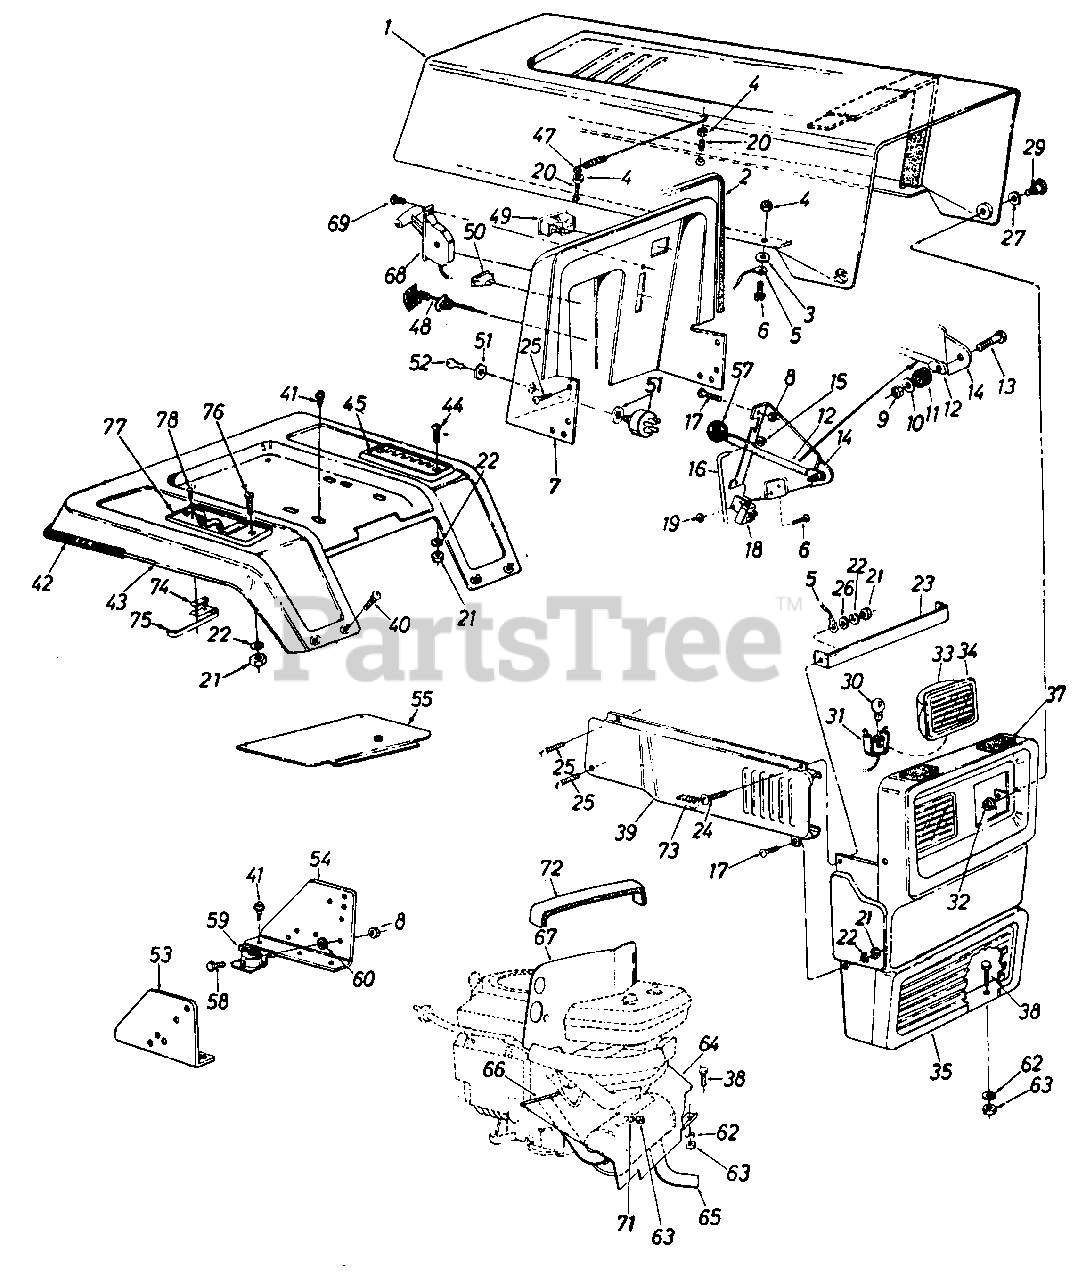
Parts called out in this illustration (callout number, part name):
3	Fl-Wash. .20" I.D. x .41" O.D.
4	Hex Sems Nut #10-24 Thd.
5	Hood Stop
6	Truss Mach. Scr. #10-24 x .5" Lg.
9	Hex L-Nut 1/4-20 Thd.
10	Fl-Wash. .281" I.D. x .73" O.D.
11	Rubber Washer
12	PTO Lever
13	Hex Bolt 1/4-20 x 1.25" Lg.
14	Deck Clutch Control Brkt.
15	Push Cap
16	Deck Control Rod
17	Truss Mach. Scr. 1/4-20 x .5" Lg.
18	Safety Switch
19	Hex Nut #10-24 Thd.
20	Hex Bolt 10-24 x 1.0" Lg.
21	Hex Nut 1/4-20 Thd.
22	L-Wash. 1/4" I.D.
23	Tie Strap Grille
24	Truss Mach. Scr. 1/4-20 x .75" Lg.
25	Hex TT-Tap Scr. 1/4-20 x .75" Lg.
26	Fl-Wash. .25" I.D. x .62"
27	Spr. Wash. .39" I.D. x .62"
29	Shld. Bolt .375" Dia. x .125" Lg.
30	Lamp
31	Socket
32	Locking Flange Nut 1/4-28 Thd.
33	Headlight Housing
34	Headlight Lens
38	Hex Bolt 5/16-18 x .75" Lg.
41	Hex Wash. AB-Tap Scr. 5/16 x .75" Lg.
42	Trim Strip-81" Lg.
45	7-Speed Selector Plate
47	Hood Spring
48	Choke Control 46" Lg.
49	Ammeter
50	Light Switch
51	Ignition Switch
52	Ignition Key
57	Knob-Blade Clutch
58	Hex Bolt 1/4-20 x .5" Lg.
59	Solenoid
60	Ext. L-Wash. 1/4" I.D.
62	L-Wash. 5/16" I.D.
63	Hex Nut 5/16-18 Thd.
64	Front Heat Shield
65	Muffler
66	Trim Strip 12" Lg.
67	Top Shield
68	Throttle Control Box Ass'y.
69	Truss Mach. AB-Tap Scr. #10 x .5" Lg.
71	Spec. L-Wash. 5/16n I.D.
72	PVC Foam
73	Rubber Strip
74	Insulator Nut Plate
75	Reverse Safety Switch
76	Truss Mach. Scr. 1/4-20 x .75" Lg.
77	Forward/Reverse Index Brkt.
78	Hex Wash. Hd. AB-Tap Scr. #8 x .5" Lg.
